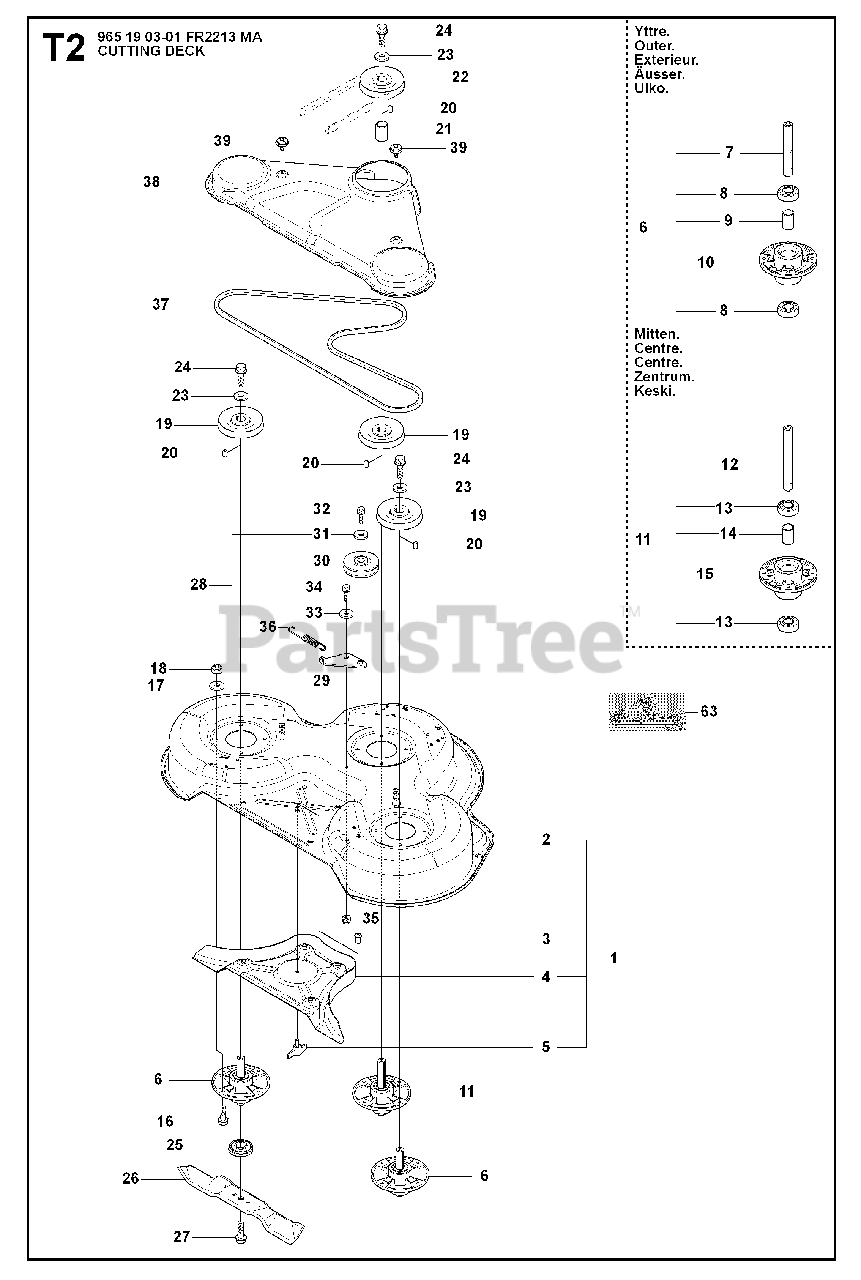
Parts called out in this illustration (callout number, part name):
6	RP SPINDLE ASSY
10	BEARING HOUSING
15	BEARING HOUSING
17	WASHER BRB 8.4X17
18	LOCKNUT M8
30	PULLEY
33	WASHER
35	LOCKNUT M8
